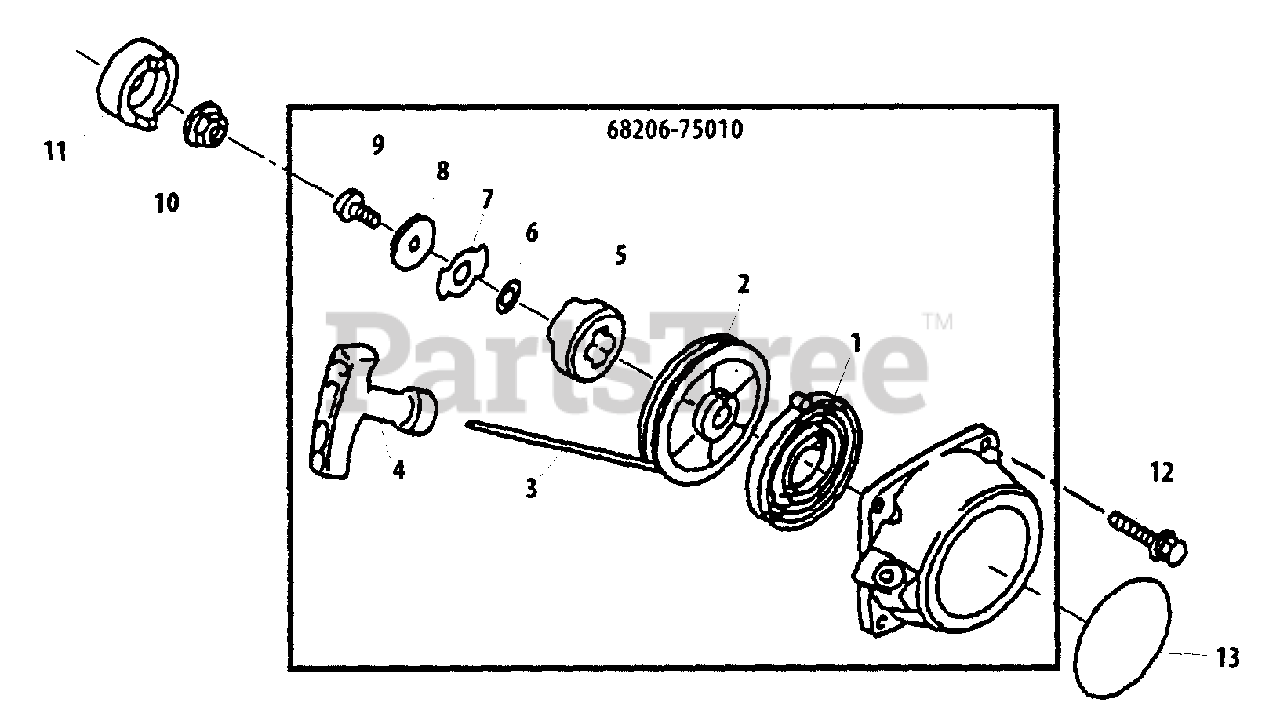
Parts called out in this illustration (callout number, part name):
1	SPRING, REWIND
2	REEL, ROPE
3	ROPE, STARTER
4	GRIP, STARTER
5	CATCHER, PAWL
7	RETAINER
9	SCREW - 8 X 1-1/4"
10	NUT - 10 -- FLANGE
11	PAWL, STARTER
12	BOLT - 5X20
13	LABEL - MODEL
68206-75010	STARTER ASSY
